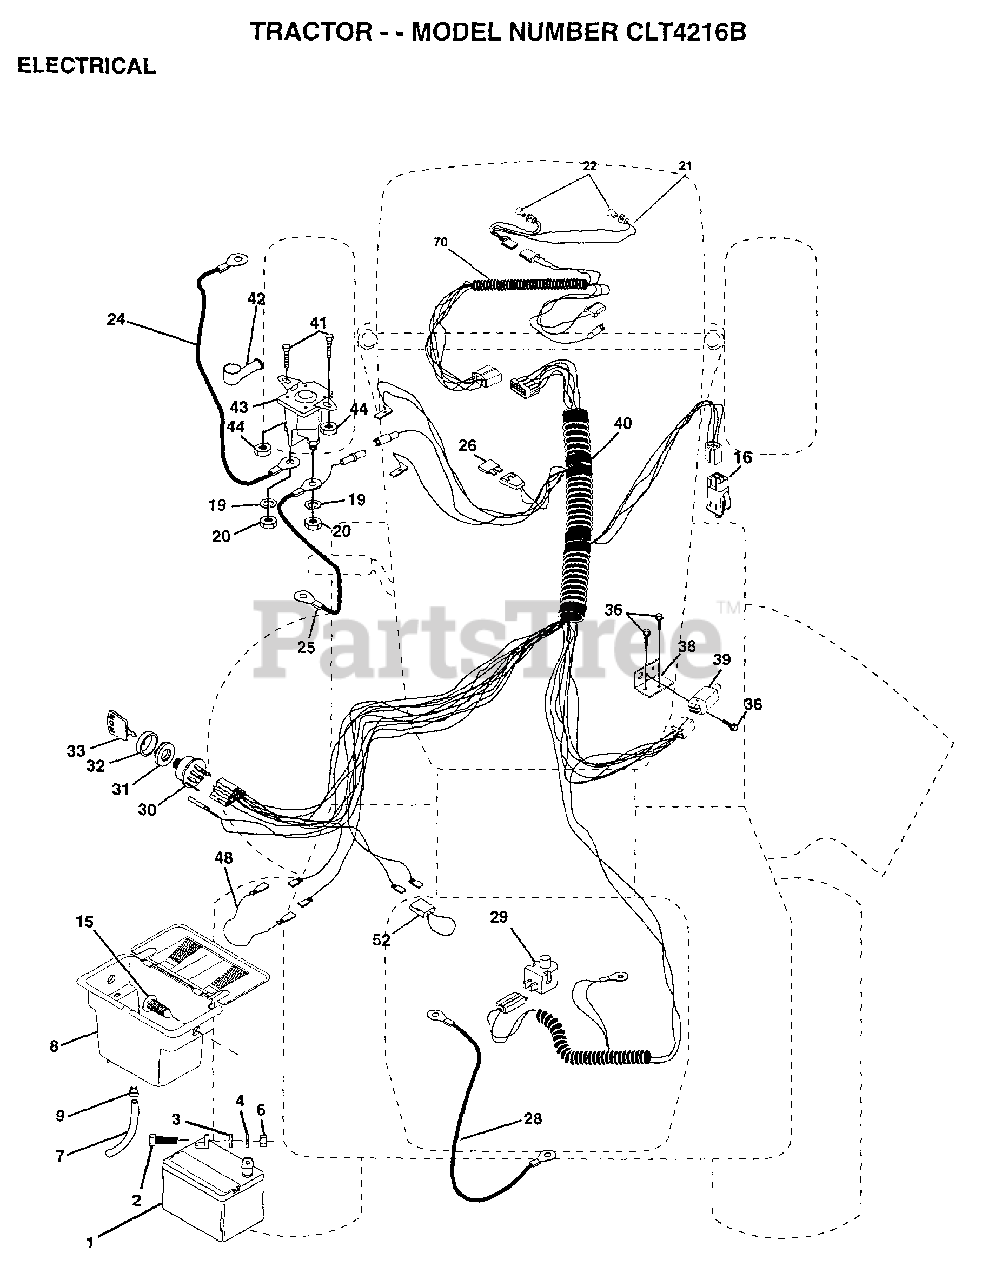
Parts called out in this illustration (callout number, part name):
2	BOLT LT
3	WASHER
4	LOCKWASHER
7	TUBE T
9	HOSE CLAMP T
15	FASTNER.SNAP-IN
16	SWITCH INTERLOCK
20	NUT
21	"HARNESS,LIGHT SOC"
22	HEADLAMP BULB
24	CABLE-BATTERY T
25	CABLE.BTRY.6GA.RD
26	FUSE HYT
28	CABLE T
29	SWITCH SEAT
30	SWITCH IGN 4POS
31	NUT IGNITION
32	COVER KEY SWITCH
33	KEY
36	SCREW
38	BRACKET SWITCH IN
39	SWITCH INTERLOCKT
40	HARNESS.IGNITION
41	BOLT HXHD FIN
44	NUT HXKEP 1/4X20
48	ADAPTER AMMETER
52	PROTECTION LOOP
70	HARNESS.ENG.LT.
